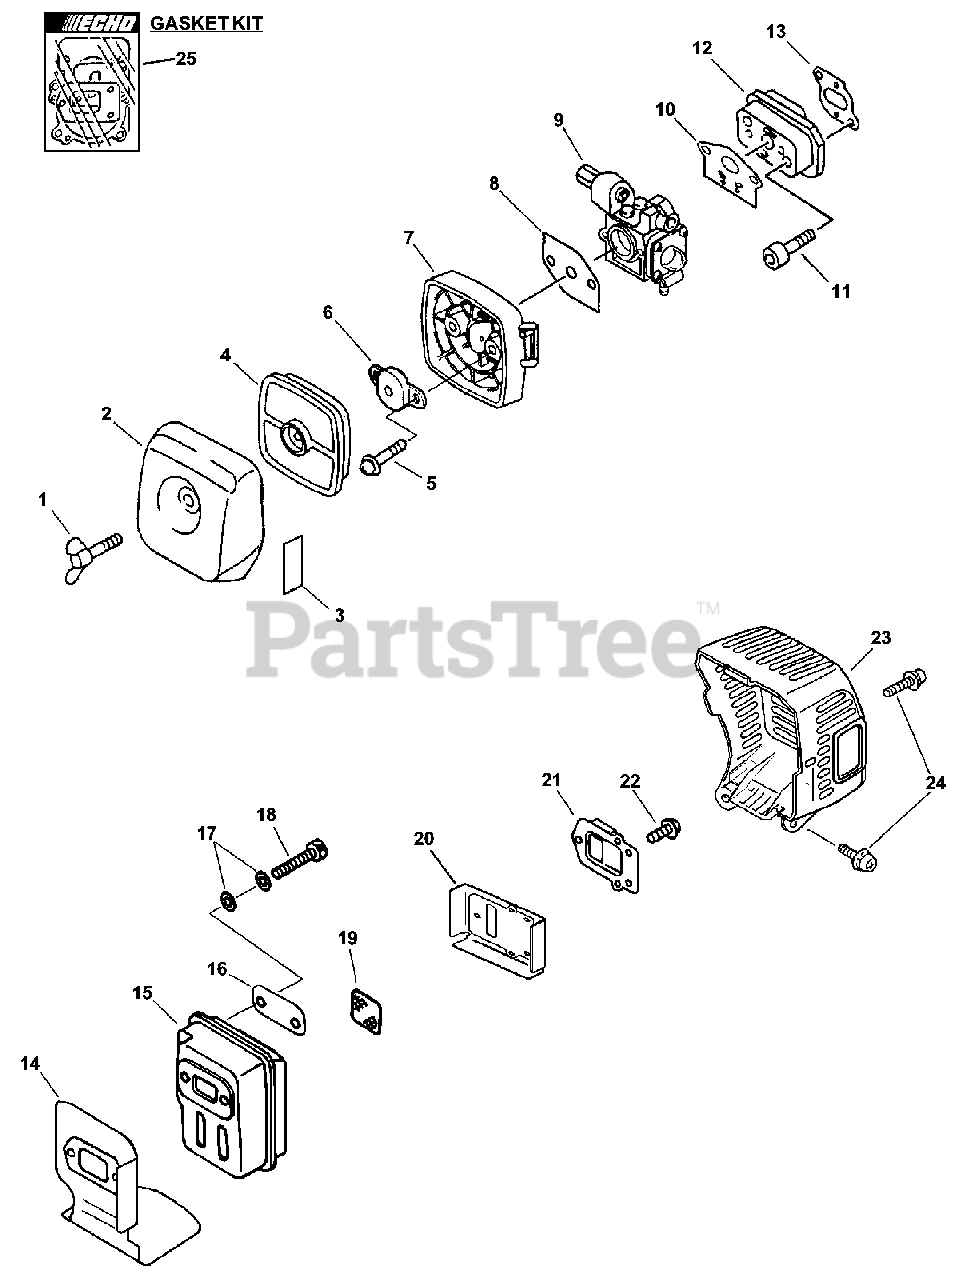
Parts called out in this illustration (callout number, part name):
1	BOLT, WING 5×20
2	COVER, AIR FILTER - GRAY
3	LABEL, CHOKE
4	FILTER, AIR - SINGLE LAYER
5	SCREW 5×60
6	PLATE, PREVENT
7	CASE, AIR FILTER - GRAY
8	GASKET, INTAKE
9	CARBURETOR - RB-K63
10	GASKET, CARBURETOR
11	BOLT 5×25
12	INSULATOR, INTAKE
13	GASKET, INTAKE
14	HEAT SHIELD, EXHAUST
15	MUFFLER
16	PLATE, EYE
17	CONICAL WASHER
18	BOLT 5×55
19	SCREEN, SPARK ARRESTER
20	GASKET, EXHAUST
21	GUIDE, EXHAUST
22	SCREW 4×10
23	COVER, EXHAUST
24	BOLT 5×12
25	GASKET KIT
